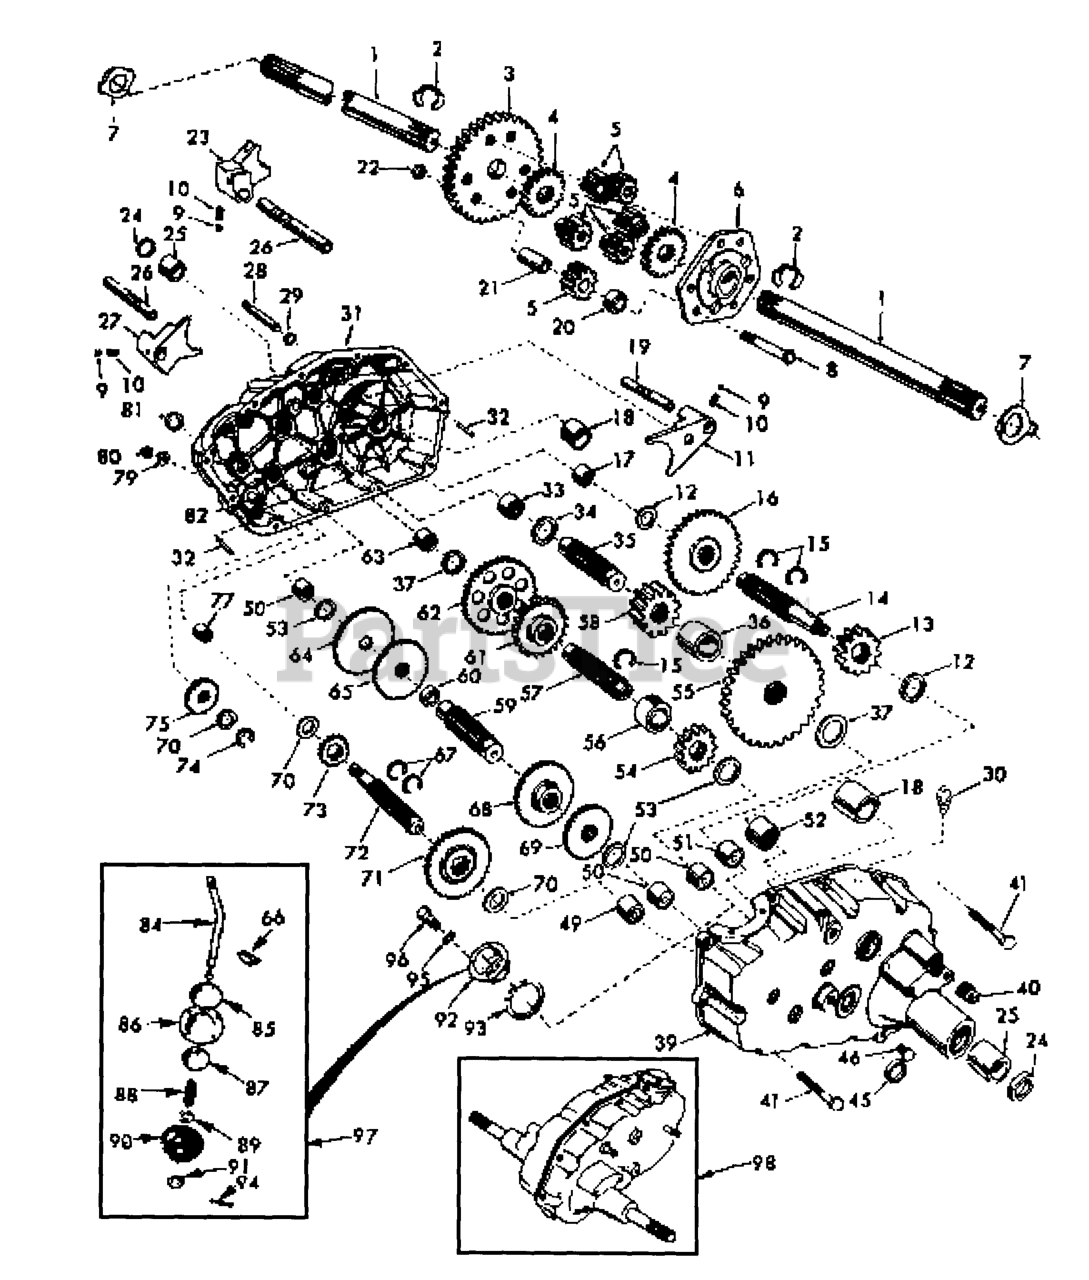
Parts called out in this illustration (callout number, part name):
1	AXLE SHAFT T
2	Retaining Ring
3	FINAL GEAR T
4	DIFF GEAR T
5	DIFF PINION T
6	DIFF CARRIER T
7	WASHER T
8	Bolt, Hex Head 3/8-24 x 3-1/4 (1" Thread Length)
9	STEEL BALL KIT
10	SPRING
12	THRUST WASHER
13	RED PINION T
14	GEAR SHAFT
15	SNAP RING T
16	GEAR T
18	BEARING
21	PINION RS
22	GRIPCO NUT
24	OIL SEAL STD
25	BRNG. T
26	SHAFT SHIFT FORK
27	SHIFT FORK T
28	SHIFT SHAFT
29	SEAL.OIL.SHAFT.SHIFT.T
31	GEARCASE.RH.W/BEARING
33	NEEDLE BRNG T
34	WASHER RACE BEARING THRUST
35	GEAR SHAFT T
36	GEAR SPACER T
39	GEARCASE LH
40	Pipe Plug 1/2-14 N.P.T.
41	BOLT.5/16-18X1.25
49	BEARING TI
50	NEEDLE BRNG T
51	NEEDLE BRNG T
52	BEARING STD
53	BRNG RACE T
54	RED PINION T
55	RED GEAR T
56	PINION SPACER T
57	GEAR SHAFT T
58	FINAL PINION T
59	GEAR SHAFT T
61	RED PINION T
62	RED GEAR T
64	LOW SPEED GEAR T
65	GEAR.REVERSE.T
67	Snap Ring, Crescent Type
68	GEAR.SPEED.INTERMEDIATE.T/A
69	HIGH SPEED GEAR T
70	THRUST WASHER
71	CLUSTER GEAR T
72	SHAFT
73	LO SPEED PINION T
75	IDLER GEAR T
77	NEEDLE BEARING TI
80	NUT **
81	SEAL STD
82	SHAFT REVERSE IDL
84	GEAR SHIFT LVR T
86	COVER AND PIN T
87	GUIDE BALL T
89	WASHER
90	SEAL.SHIFT
91	Washer 9/16x15/16x12 Gauge
92	GEAR SHIFT GATE T
94	COTTER PIN
95	WASHER.LOCK.HVY.HLCL.SPR.5/16
96	BOLT
97	GEAR SHFT LVR T
98	TRANSAXLE ASSY
